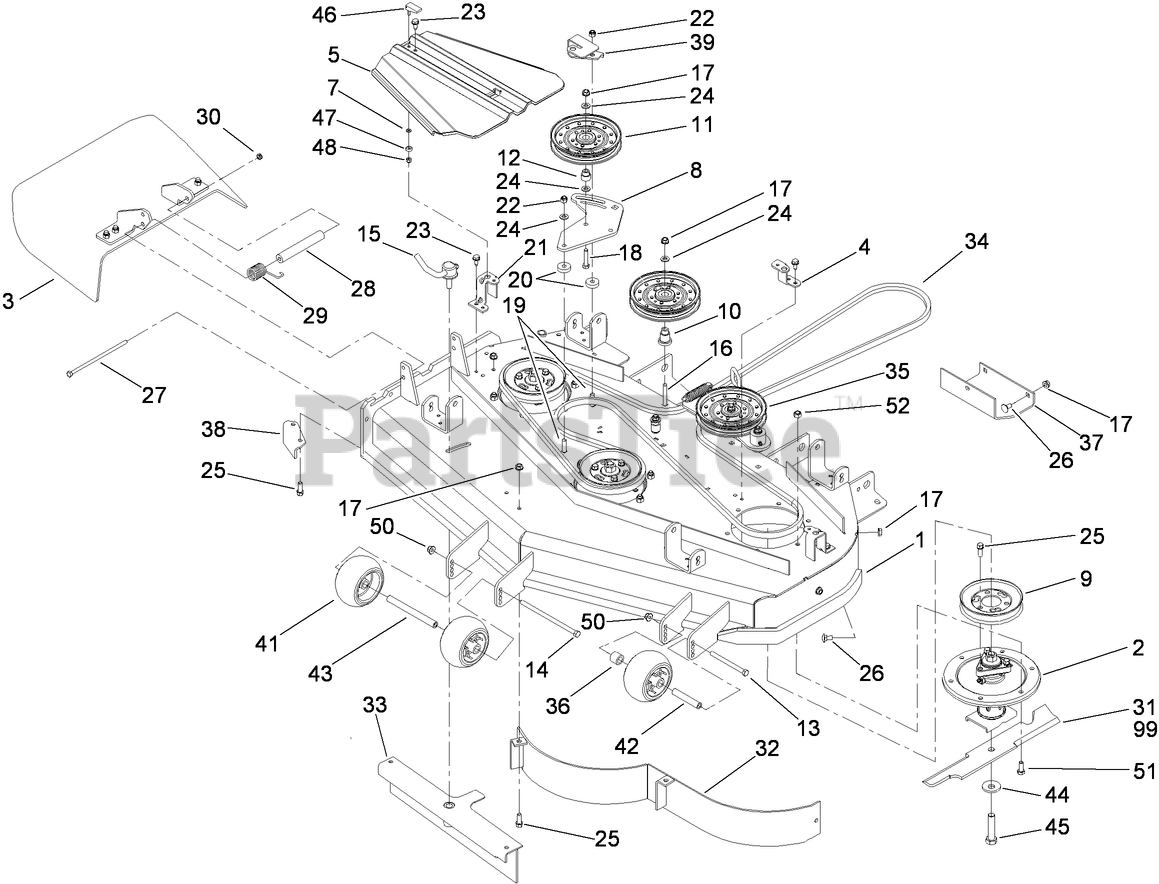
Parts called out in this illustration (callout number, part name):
1	DECK DECAL ASM
2	SPINDLE ASM
3	RUBBER DEFLECTOR ASM
4	BRACKET-COVER, TALL
5	COVER-BELT
7	WASHER
8	PLATE-IDLER
9	PULLEY
10	MOUNT-PULLEY
11	Idler-Flat
12	BUSHING-IDLER
13	SCREW-HH
14	SCREW-HH
15	LEVER ASM
16	SCREW-CARR
17	NUT-HHF, WHIZ
18	SCREW-HH
19	SCREW-CARR
20	Spacer
21	BRACKET-COVER
22	NUT-LOCK, NI
23	SCREW-HWHTF
24	WASHER-FLAT
25	SCREW-HWH
26	SCREW-CARR
27	SCREW-HH
28	SPACER
29	SPRING-TORSION
30	NUT-LOCK, NI
31	BLADE-16.5 INCH (HIGH FLOW)
32	BAFFLE ASM
33	BAFFLE
34	BELT-V
35	SPRING IDLER ASM
36	TUBE-SPACER
38	BAFFLE-DISCHARGE
39	BRACKET-COVER
41	ROLLER-SCALP, ANTI
42	TUBE-SPANNER
43	SPACER-WHEEL
44	Washer-Blade Bolt, Heavy
45	Screw-Cap
46	HANDLE-LATCH, SWELL
47	BUSHING-LATCH, SWELL
48	NUT-LOCK, HH
50	NUT-HF, NI
51	SCREW-HH
52	NUT-LOCK, NI
99	BLADE-ROTARY, 16.5 INCH (LOW FLOW)
99	BLADE-ROTARY, 16.5 INCH (MED FLOW)
99	BLADE-ROTARY, 16.5 INCH (ATOMIC)
99	BLADE-RECYCLER, 16.5 INCH
